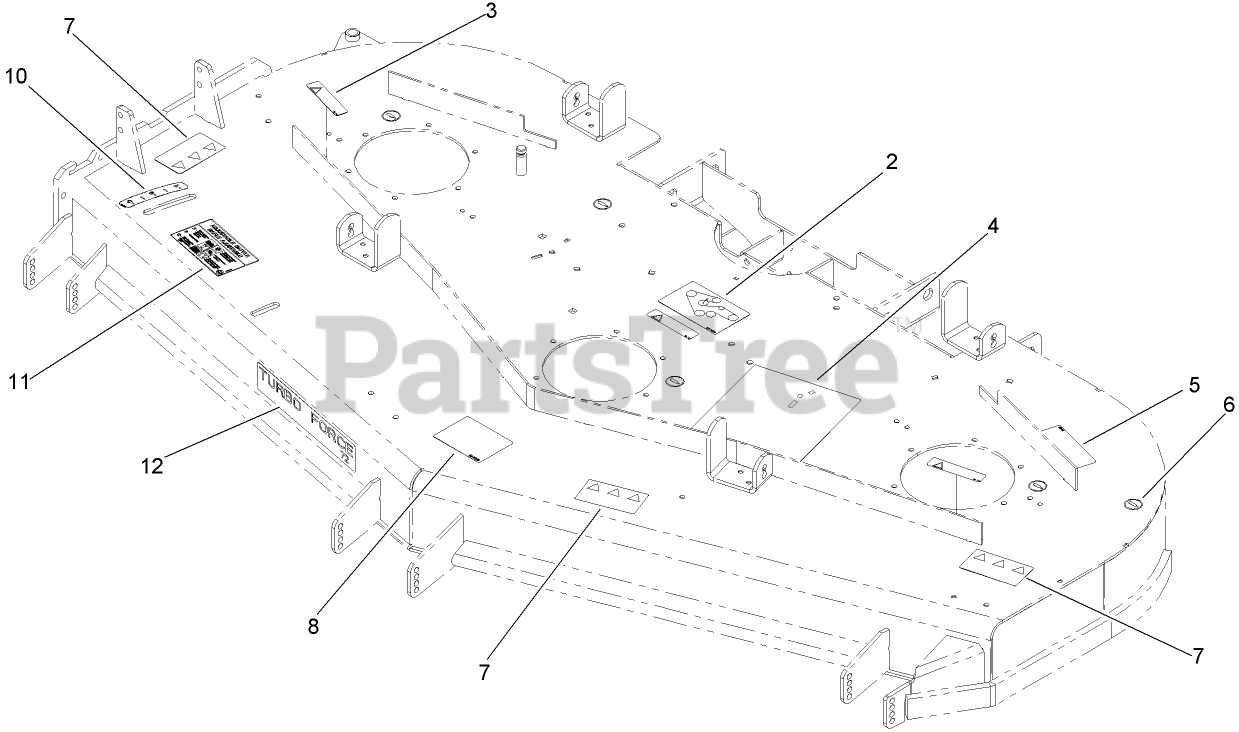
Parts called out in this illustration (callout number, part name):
2	DECAL-ROUTING, BELT
3	DECAL-WARNING
4	DECAL-CHECK, SERVICE
5	DECAL-TORQUE, BLADE BOLT
6	DECAL-GREASE
7	DECAL-DANGER
8	DECAL-ANTI SCALP
10	DECAL-SETTING, BAFFLE
11	DECAL-ADJUSTMENT, BAFFLE
